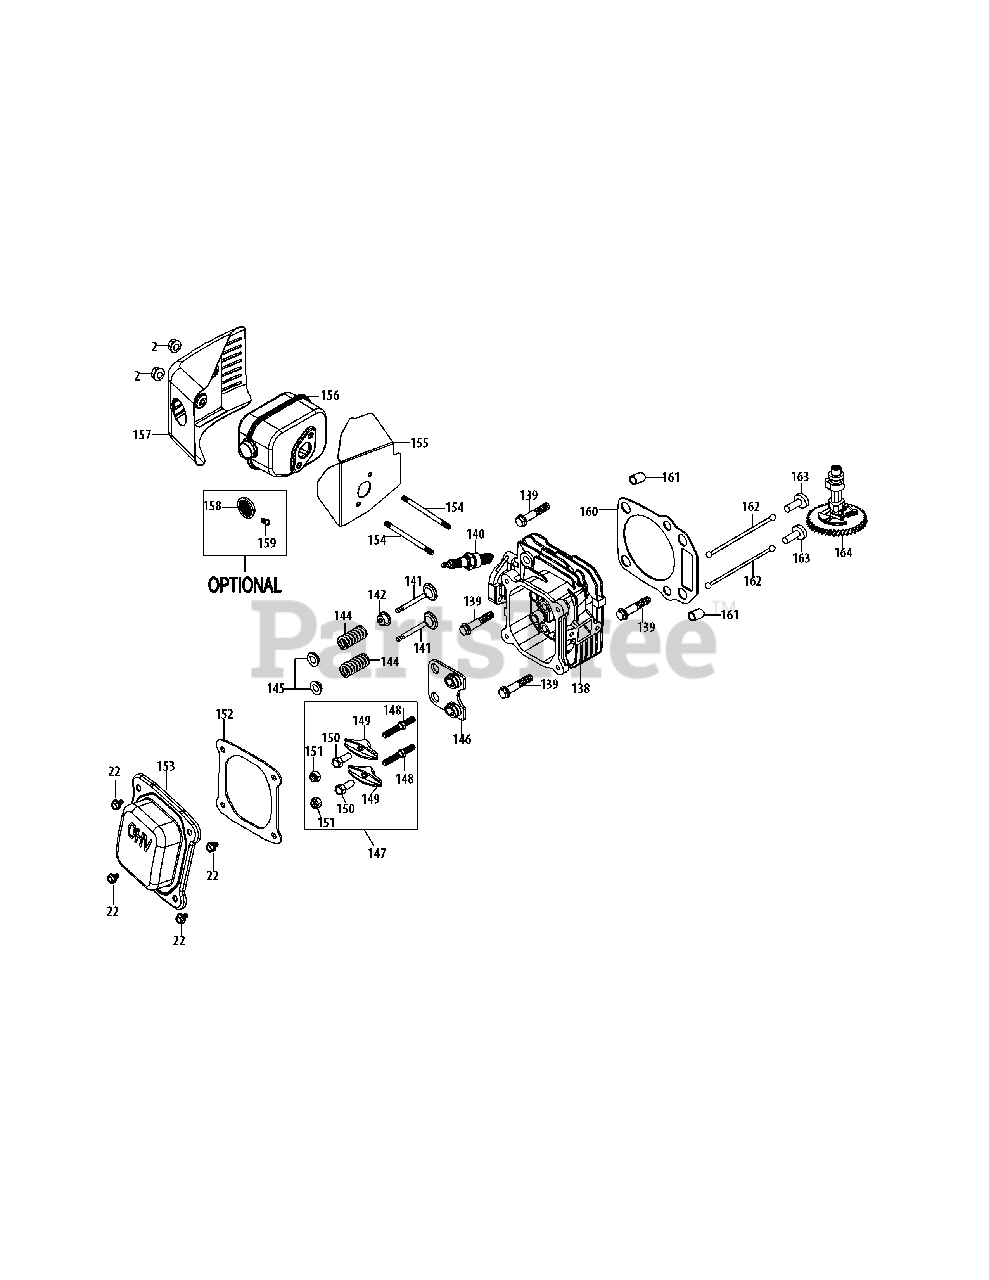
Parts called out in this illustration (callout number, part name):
2	Nut M6
22	Bolt M6×14
138	Cylinder Head Assembly
139	Head Bolt M8×54
140	Spark Plug/F6Rtc
141	Valve Kit
142	Intake Valve Seal
143	Valve Kit
144	Valve Spring
145	Valve Spring Retainer
146	Push Rod Guide
147	Rocker Arm Assembly
148	Rocker Arm Stud
149	Rocker Arm
150	Valve Adjusting
151	Pivot Locking Nut
152	Valve Cover Gasket
153	Valve Cover
154	Muffler stud M6×95
154	Muffler Stud Assemlby
155	Muffler Gasket
156	Muffler Assembly
157	Muffler Shield
158	Spark Arrestor
159	Spark Arrestor Screw
160	Cylinder Head Gasket
161	Dowel Pin 10×16
162	Push Rod Kit
163	Tappet
164	Camshaft Assembly
